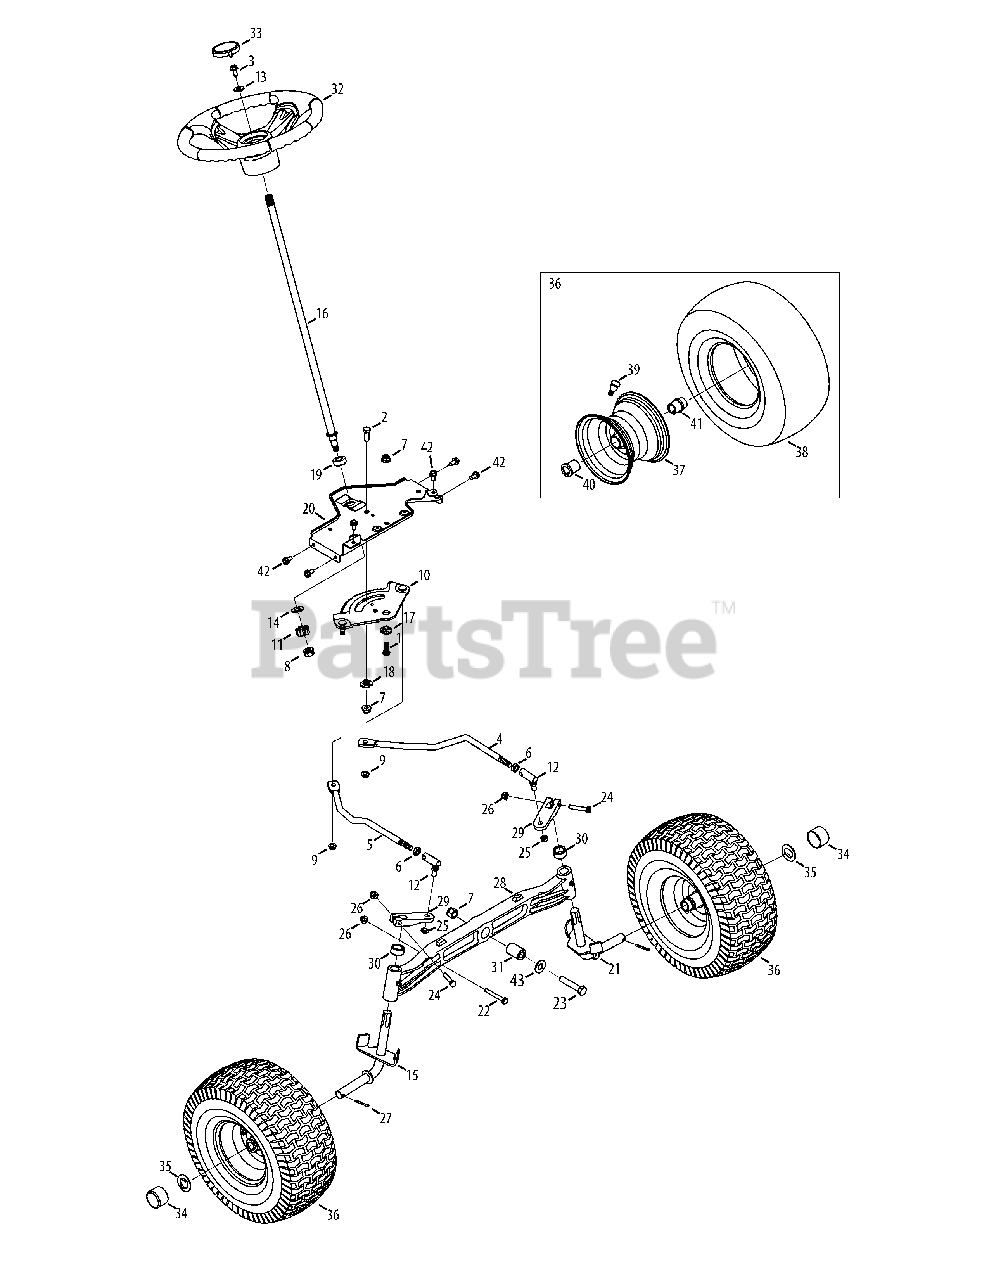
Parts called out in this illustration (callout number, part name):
1	Hex Head Screw, 3/8-16 x 1.00
2	Hex Head Screw, 3/8-16 x 1.00
3	Hex Head Screw, 5/16-18 x 1.00
4	LH Drag Link
5	RH Drag Link
6	Jam Nut, 7/16-20
7	Flangelock Nut, 3/8-16
8	Flangelock Nut, 7/16-20
9	Flangelock Nut, 5/16-18
10	Steering Gear
11	Steering Pinion Gear
12	Ball Joint, 7/16-20
13	Flat Washer, .406 x .875 x .105
14	Flat Washer, .51 x 1.12 x .06 HT
15	RH Axle Assembly
16	Steering Shaft, .625 OD x 24.25 LG
17	Shoulder Spacer, .385X 1.25 x .3025
18	Spacer, .38 x 1.375
19	Hex Flange Bearing 5/8 PM
20	Steering Support Bracket
21	LH Axle Assembly
22	Hex Head Screw, 5/16-18 x 2.25
23	Hex Head Screw, 3/8-16 x 2.50
24	Hex Head Screw, 5/16-18 x 1.75
25	Hexlock Nut, 3/8-24
26	Flangelock Nut, 5/16-18
27	Cotter Pin, 5/32 x 1.25
28	Pivot Bar Axle
29	Steering Block
30	Spacer, .71 ID x .125 OD x .56LG
31	Spacer, .385 x 1.00 x 1.5075
32	Steering Wheel, Soft Grip
33	Cap, Troy-Bilt
34	Bumper Cap
35	Flat Washer, .781ID x 1.590OD
36	Wheel Assembly
37	Rim Assembly
39	Tubeless Air Valve
40	Flange Bearing, .760 x 1.00 x 1.20LG
41	Flange Bearing, .760ID
42	Screw, Self-tapping, 5/16-18, .750,
43	Washer, Flat, .406 x .875 x .059
